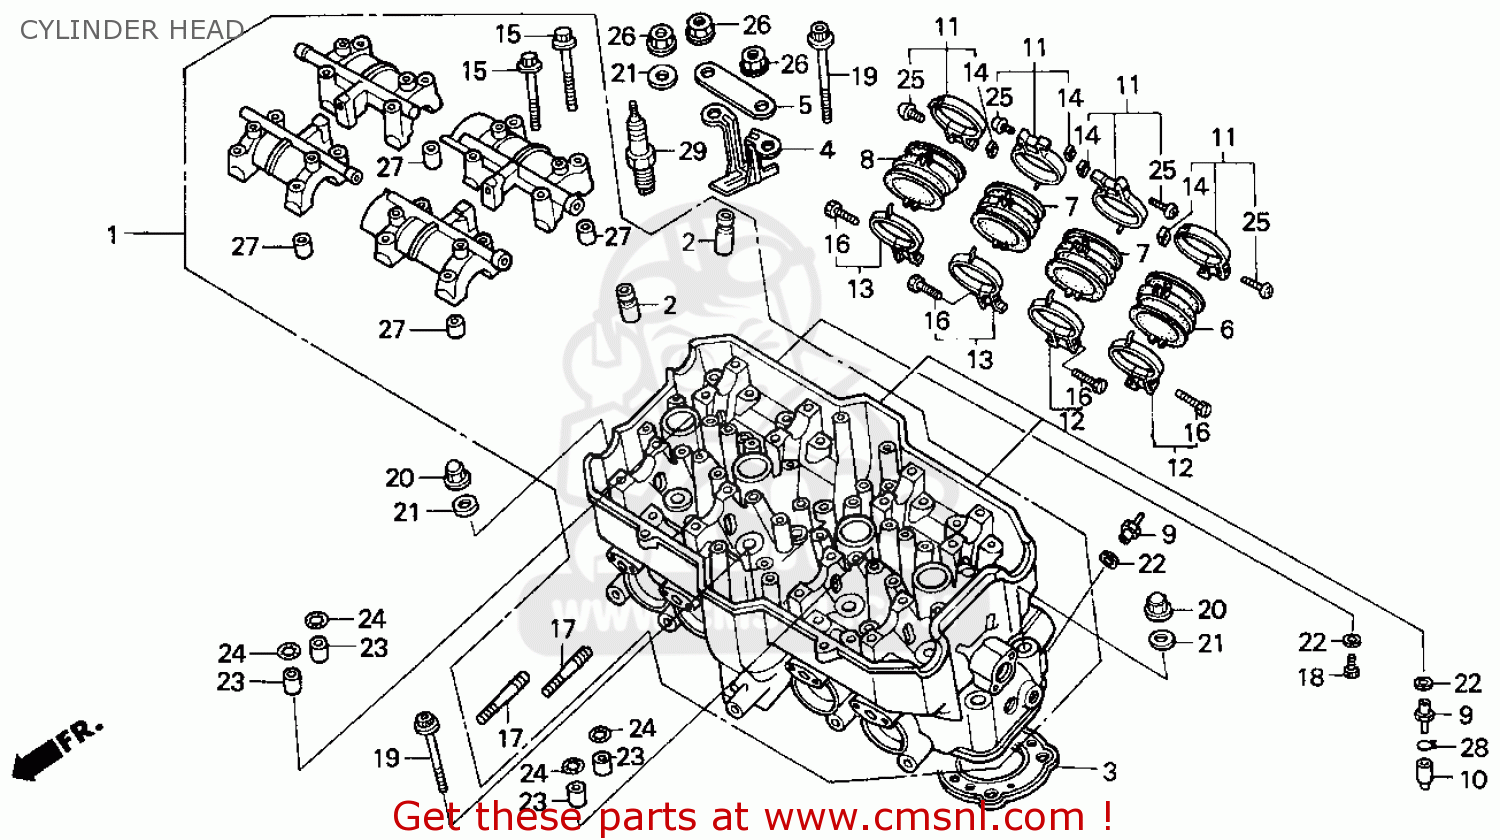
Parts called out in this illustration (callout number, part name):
1	HEAD ASSY,CYLINDE
2	GUIDE,VALVE
3	GASKET,CYLINDER H (NAS)
4	PLATE,OIL GUIDE
5	PLATE,OIL GUIDE S
6	INSULATOR A,CARBU
7	INSULATOR B,CARBU
8	INSULATOR C,CARB
9	JOINT,BOOST
10	CAP,BOOST
11	BAND A,INSULATOR
12	BAND C,INSULATOR
13	BAND B,INSULATOR
14	NUT,SQUARE,5MM
15	BOLT,FLANGE 6X48
16	BOLT,RECESSED,5X2
17	BOLT,STUD 8X24
18	BOLT,SOCKET,5X8
19	BOLT,SOCKET,8X55
20	NUT,FLA.CAP 10MM
21	WASHER,10MM
22	WASHER 5MM
23	PIN, DOWEL, 8X8
24	O-RING,7.5X1.5
25	SCREW, PAN, 5X32
28	CLIP B7,TUBE
29	SPARK PLUG (ND)
